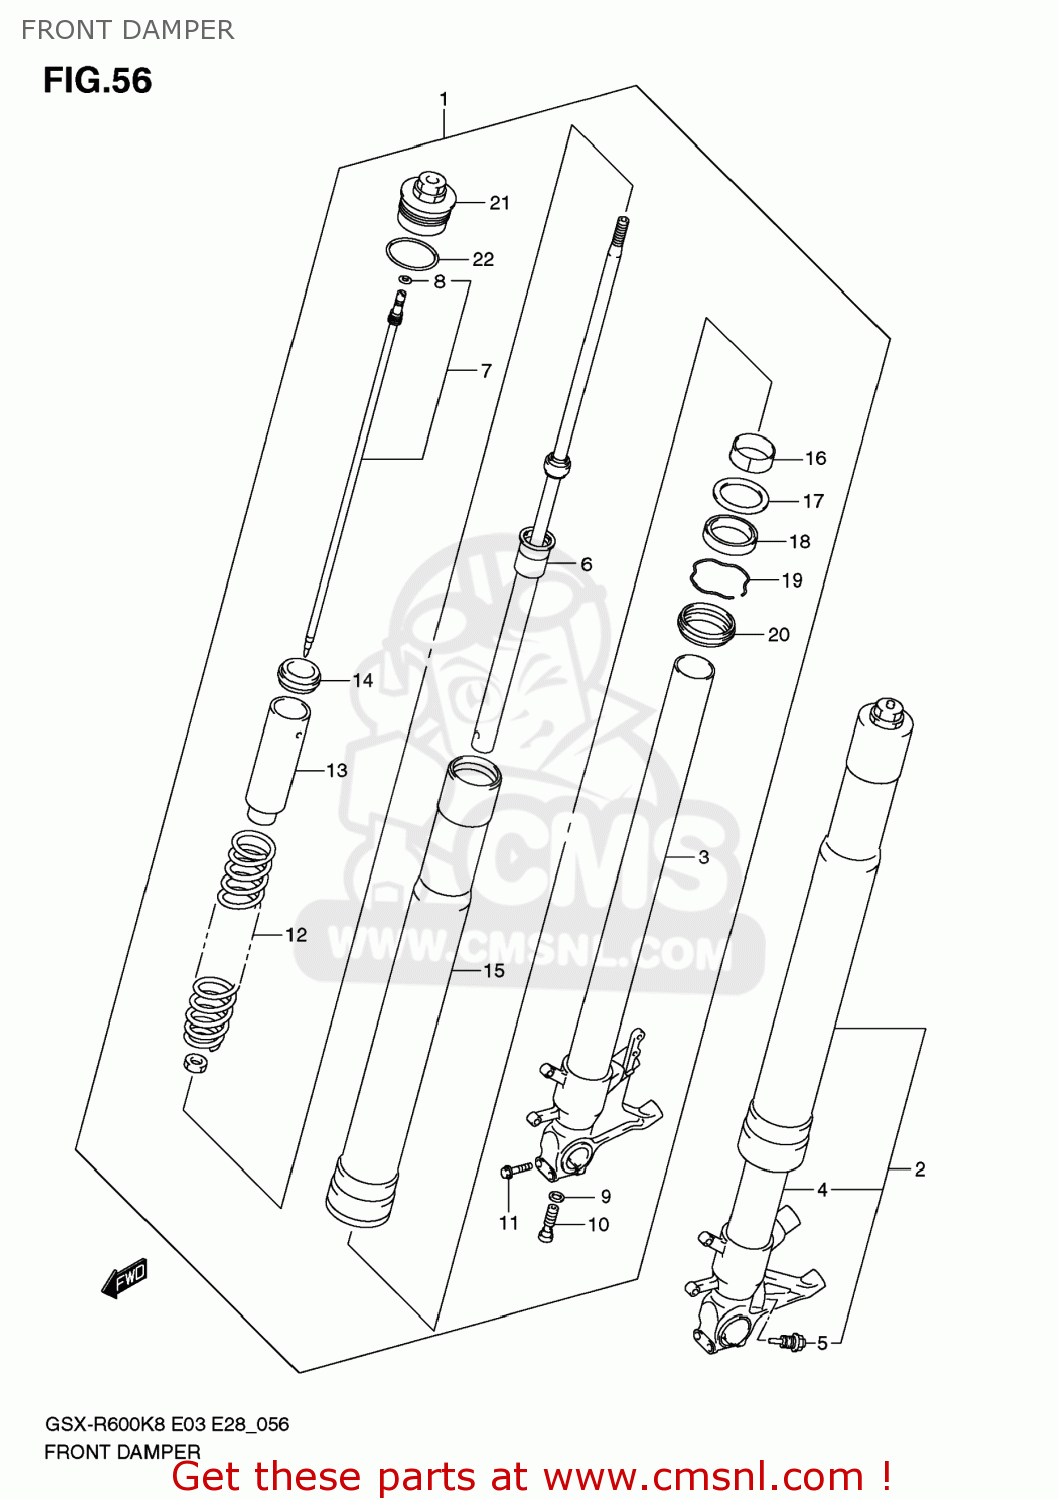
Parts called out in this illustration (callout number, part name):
1	DAMPER ASSY,FR FORK,R
2	DAMPER ASSY,FR FORK,L
3	TUBE,INNER,R
4	TUBE,INNER,L
5	PIECE,ADJUST
6	DAMPER,FR
7	PUSH ROD
8	O RING(D:1.9,ID:3.8)
9	WASHER(10X15X1.5)
10	BOLT
11	BOLT
12	SPRING,FR
13	COLLAR,SPRING
14	GUIDE,SPRING UPR
15	TUBE,OUTER
16	BUSH,GUIDE
17	SPACER,SEAL
18	SEAL,OIL
19	CIRCLIP,FORK OIL SEAL
20	SEAL,DUST
21	BOLT,FORK
22	O RING,FORK BOLT
